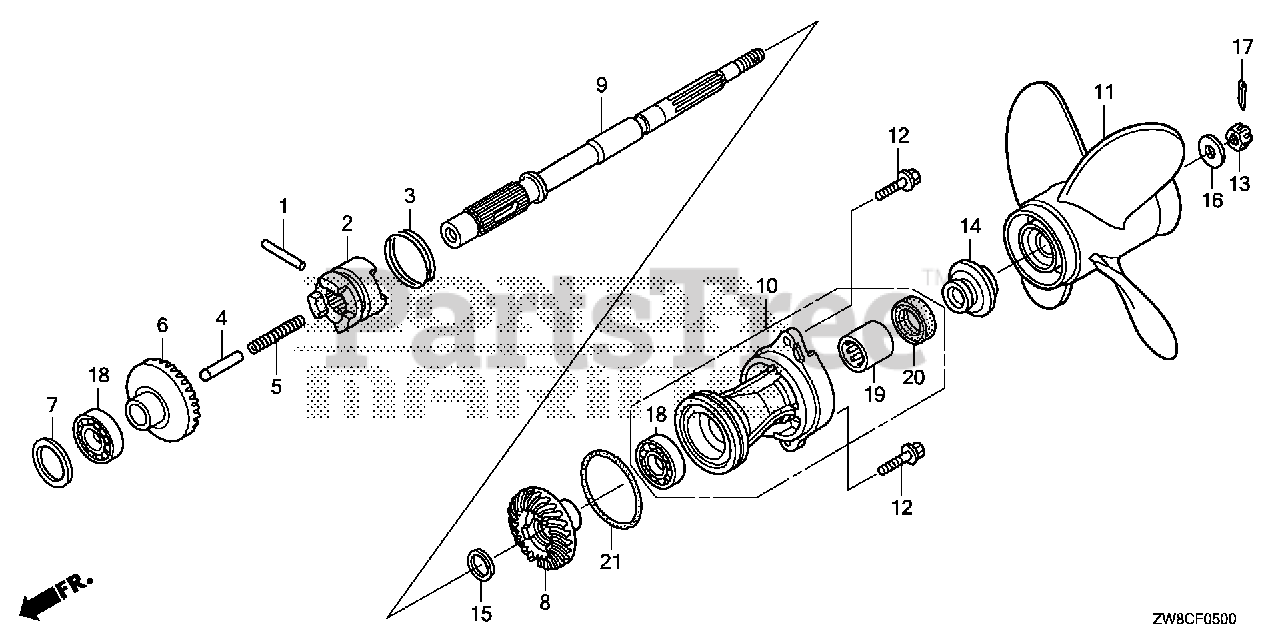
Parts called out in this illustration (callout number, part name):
1	ROLLER (4X29.8)
2	SHIFTER, CLUTCH
3	RING, CROSS PIN
4	SLIDER, SHIFT
5	SPRING, SHIFT
6	GEAR, FR. BEVEL
7	SHIM A (40MM)
7	SHIM B (40MM)
7	SHIM C (40MM)
8	GEAR, RR. BEVEL
9	SHAFT, PROPELLER
10	HOLDER ASSY., PROPELLER SHAFT *NHB14M* (AQUA MARINE SILVER METALLIC)
11	PROPELLER, FOUR BLADES (10X6-1/2 HT) *NH283* (STIN GRAY)
11	PROPELLER, FOUR BLADES (9-1/4X7) *NH283*
11	PROPELLER, FOUR BLADES (9-1/4X8) *NH283* (STIN GRAY)
11	PROPELLER, FOUR BLADES (9-1/4X9) *NH283* (STIN GRAY)
11	PROPELLER, FOUR BLADES (9-1/4X10) *NH283*
12	BOLT, FLANGE (6X20) (ENGINE NO.)
13	NUT, CASTLE (10MM)
14	WASHER, PROPELLER THRUST
15	WASHER (18MM)
16	WASHER (10MM)
17	PIN, COTTER (3MM)
18	BEARING, RADIAL BALL (25X47X12)
19	BEARING, NEEDLE (17X24X20) (NTN)
20	SEAL, WATER (17MM)
21	O-RING (59.4X3.1)
